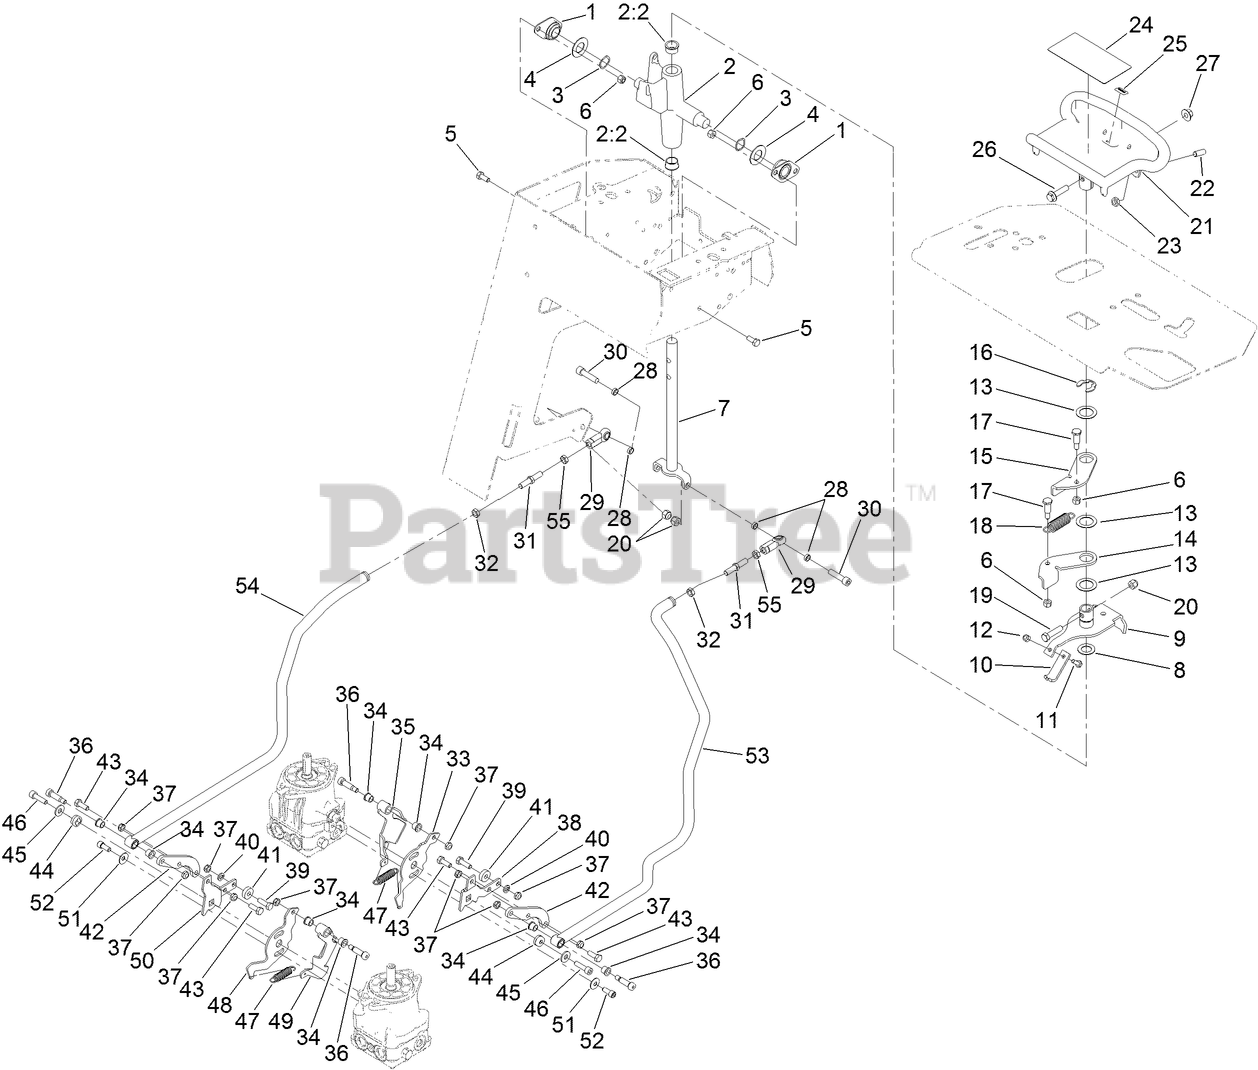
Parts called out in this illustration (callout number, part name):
1	BEARING
2	CONTROL SUPPORT ASM
2:2	BEARING-FLANGE
3	WASHER-SPRING, WAVE
4	WASHER-FLAT
5	SCREW-HH
6	NUT-LOCK, NI
7	ROD-DRIVE
8	WASHER-THRUST
9	LEVER-PIVOT
10	PLATE-NEUTRAL
11	SCREW-HH
12	NUT-LOCK, NI
13	WASHER-PLAIN
14	LEVER-RETURN, RH
15	LEVER-RETURN, LH
16	RING-RETAINING
17	SCREW-SHOULDER
18	SPRING-EXTENSION
19	SCREW-HH
20	NUT-LOCK, NI
21	HANDLE-CONTROL
22	SCREW-SET
23	NUT-JAM
24	DECAL-TRACTION
25	DECAL
26	SCREW-HHF
27	NUT-FLANGE
28	SPACER-PLATE, RETAINING
29	JOINT-BALL END, LH
30	SCREW-HSH
31	SCREW-JACK, CONTROL
32	NUT-HJ
33	PLATE-BASE, LH
34	BUSHING-FLANGE
35	PIVOT-LH
36	BOLT-SHOULDER
37	NUT-LOCK, NI
38	PLATE-ARM, RETURN, LH
39	SCREW-HH
40	SCREW-HH
41	BEARING-BALL
42	PLATE-ADAPTER, CONTROL, RH
43	SCREW-HH
44	LOCK-TRUNION
45	WASHER-FLAT
46	SCREW-HSH
47	SPRING-EXTENSION
48	PLATE-BASE, RH
49	PIVOT-RH
50	PLATE-ARM, RETURN
51	WASHER-BELLEVILLE
52	SCREW-HSH
53	LINK-STEERING, LH
54	LINK-STEERING, RH
55	NUT-JAM, LH
